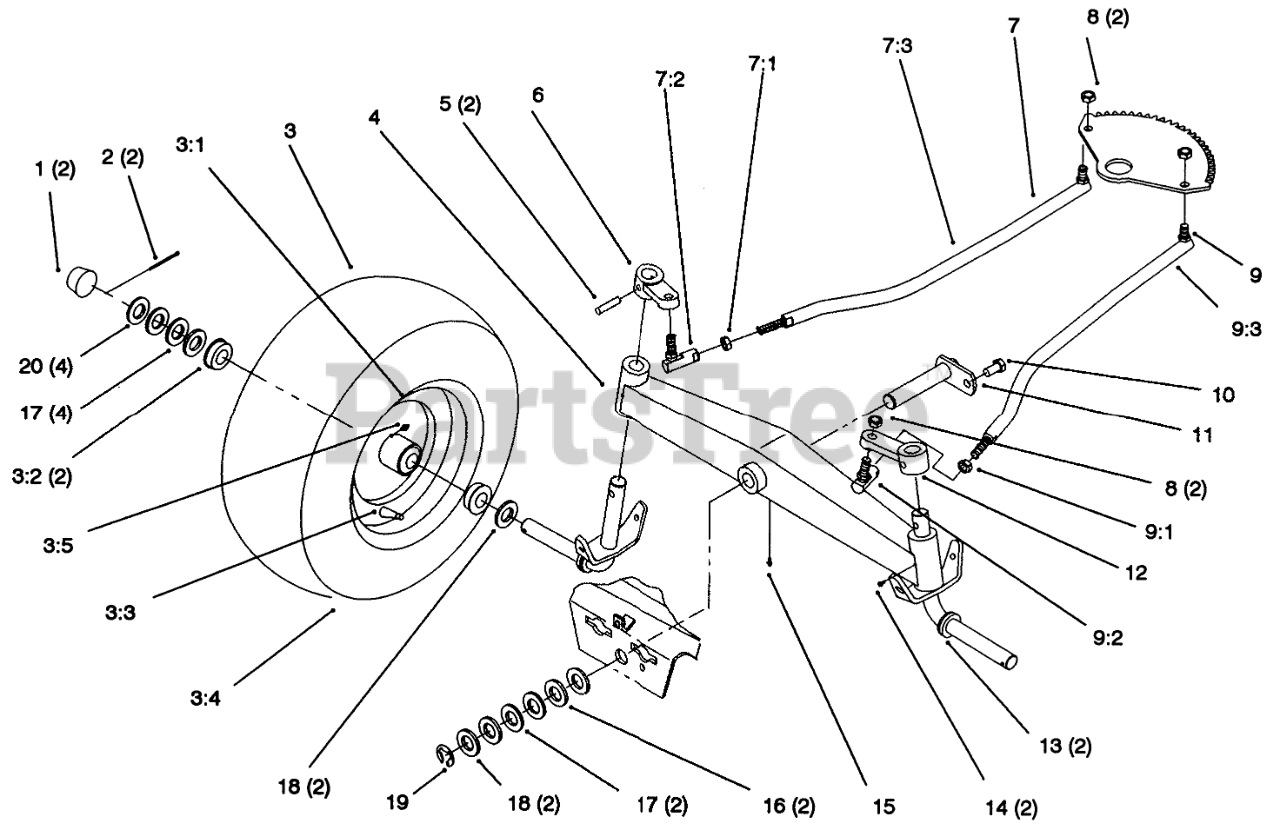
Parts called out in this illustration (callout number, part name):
1	CAP-HUB
2	PIN-COTTER
3	ASM-Wheel & Tire
3:1	Wheel ASM
3:2	BEARING-WHEEL
3:3	VALVE
3:4	Tire (16 x 6.5-8) 2-Ply -2 Wheel Axel
3:5	ZERK-GREASE
4	AXLE-FRONT
6	Arm-Front Spindle
7	LINKAGE-STEERING, RH
7:1	Nut-Hex Jam
7:2	BALL-JOINT
7:3	Ball Link ASM
9	Steering Link LH
9:1	Nut-Hex Jam
9:2	BALL-JOINT
9:3	Ball Link ASM
10	SCREW-HWH, TAPTITE
11	Pin-Front
12	Arm-Front Spindle
13	SPINDLE
14	FITTING-GREASE
15	FITTING-LUBE, 45 DEG
16	Washer
17	WASHER
18	WASHER-SHIM
19	E-RING
20	WASHER-PLAIN
21	8"-HUB CAP LOGO
